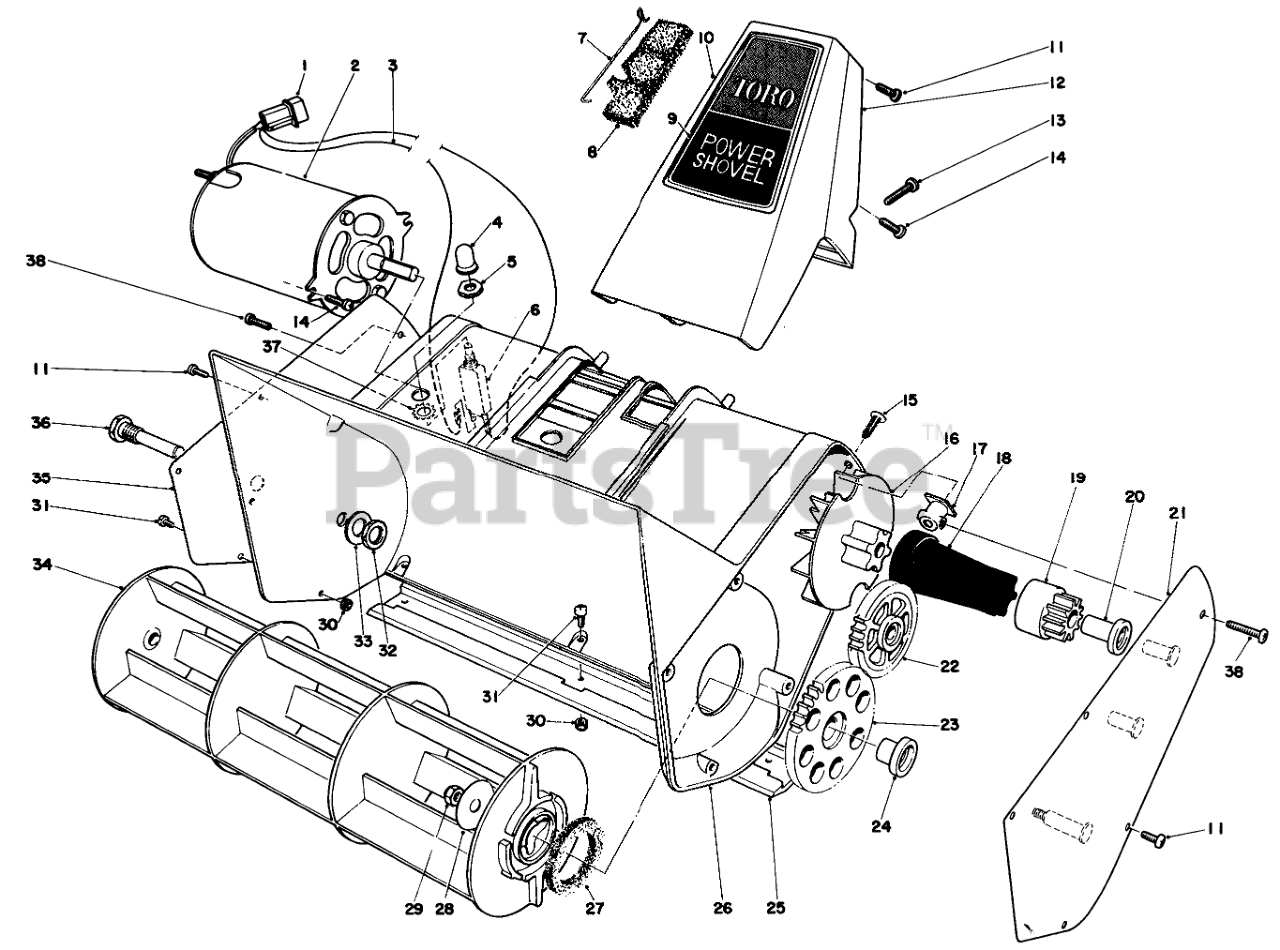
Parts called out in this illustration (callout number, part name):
1	Pin Housing
2	Motor
3	WIRE ASS'Y
4	Circuit Breaker Seal
5	Hex Nut
6	Circuit Breaker (Incl. Ref. #5)
7	RETAINER - FILTER
8	FOAM FILTER
9	HANDLE SUPT DECAL
10	FRONT SUPPORT
11	SCREW-PPH
12	Handle Support-Back
13	SCREW-PPH
14	SCREW-PPH
15	XMAS TREE FASTENER
16	FAN, POWER SHOVEL
17	MTG BLOCK
18	DRIVE COUPLING
19	Drive Gear (Incl. Ref. #20)
20	BUSHING, DRIVE GEAR
21	Gear Carrier
22	Idler Gear
23	Rotor Gear (Incl. Ref. #24)
24	BUSHING, ROTOR GEAR
25	Scraper
26	Housing
27	FELT WASHER
28	ROTOR WASHER
29	NUT-LOCK, NI
30	NUT-LOCK
31	SCREW-PPH
32	3/8 24 JAM NUT
33	WASHER-FLAT
34	ROTOR
35	RT. SIDE COVER (RAW)
36	ROTOR PIN
37	WASHER-LOCK/EXT
38	Screw
